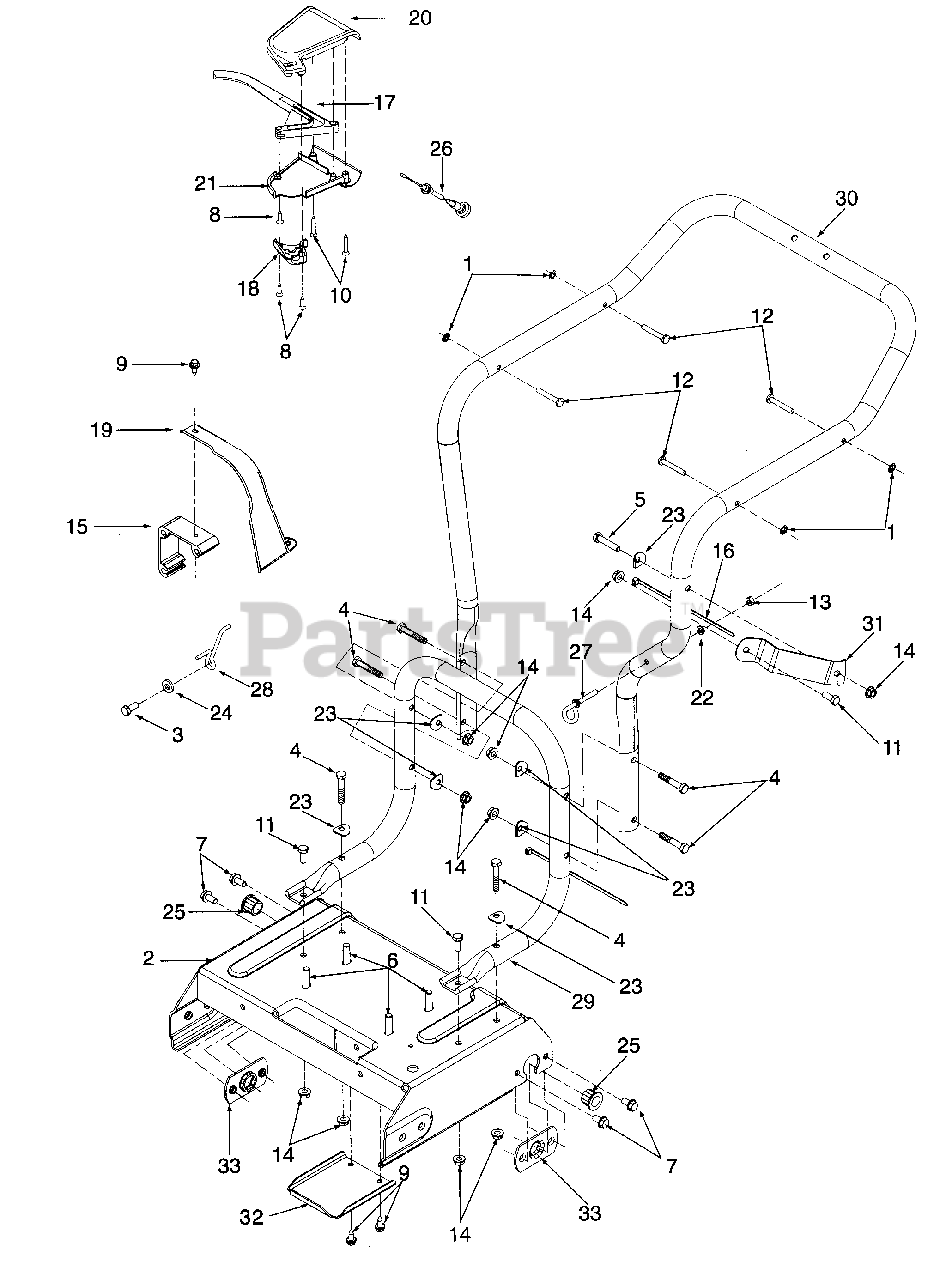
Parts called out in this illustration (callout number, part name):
1	Nut, Push, .25
3	Screw, Hex Cap, 5/16-24 x .75 GR5
4	Screw, Hex Cap, 5/16-18 x 1.75
5	Screw, Hex Cap, 5/16-18 x 1.5
6	Screw, Hex Wash Hd Tapp, 3/8-16 x 1.25
7	Screw, Hex Wash Hd Tapp, 5/16-18 x .62
8	Screw, Phil Cntrsnk, #10-12 x .75
9	Screw, Hex Wash Hd, 1/4-14 x .62
10	Screw, Phil Cntrsnk, #10-16 x 1.25
11	Screw, Hex Cap, 5/15-18 x .75 GR5
12	Pin, Stud, .250 x 1.75
13	Nut, Hex, 1/4-28
14	Nut, Hex Flange Lock, 5/16-18 GR5
15	Adapter, Engine Mtg
16	Cable Tie
17	Lever, Drive Control
18	Cap, Cable Mtg
19	Belt Cover
20	Upper Clutch Cover
21	Lower Clutch Cover
22	Washer, Lock, 1/4
23	Saddle Washer, .320 x .93
24	Washer, Flat, .344 x .75 x .12
25	Bearing, Flange, .631 ID x .72 OD
26	Cable, Clutch, 56.0
28	Belt Keeper
